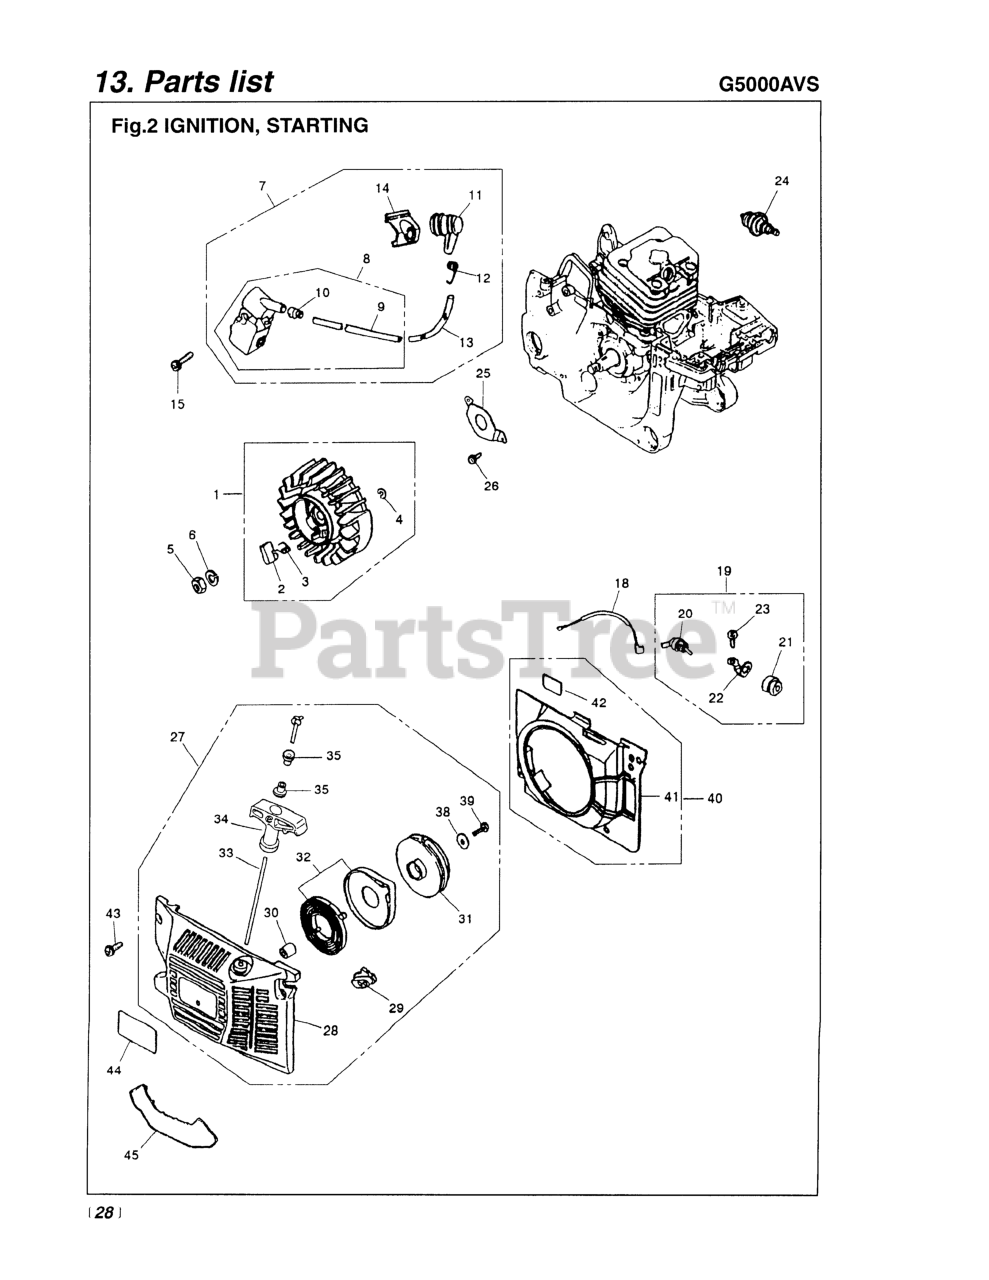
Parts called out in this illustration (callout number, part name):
3	SPRING, RETURN
4	RING, SNAP, M4
5	NUT (RPLS -43230)
6	WASHER, M8 x 20
7	COIL ASSEMBLY
8	COIL COMPLETE
9	CORD, HI TENSION
11	CAP, PLUG
12	SPRING PLUG (RPLS 3310-71320)
19	SWITCH ASSEMBLY
20	SWITCH (REPLACES 2670-71612)
21	COVER, SWITCH
22	PLATE, EARTH
23	SCREW
26	SCREW, M4 X 10
27	STARTER ASSEMBLY
28	CASE, RECOIL (RPLS 2670-75113)
31	REEL (REPLACES -75211)
32	SPRING COMP
33	ROPE (RPLS -75410)
34	KNOB
38	WASHER (USE 181741)
40	COVER COMPLETE
43	SCREW (REPLACES 2616-24320)
44	LABEL, RECOIL
45	SNOW PROTECTOR
